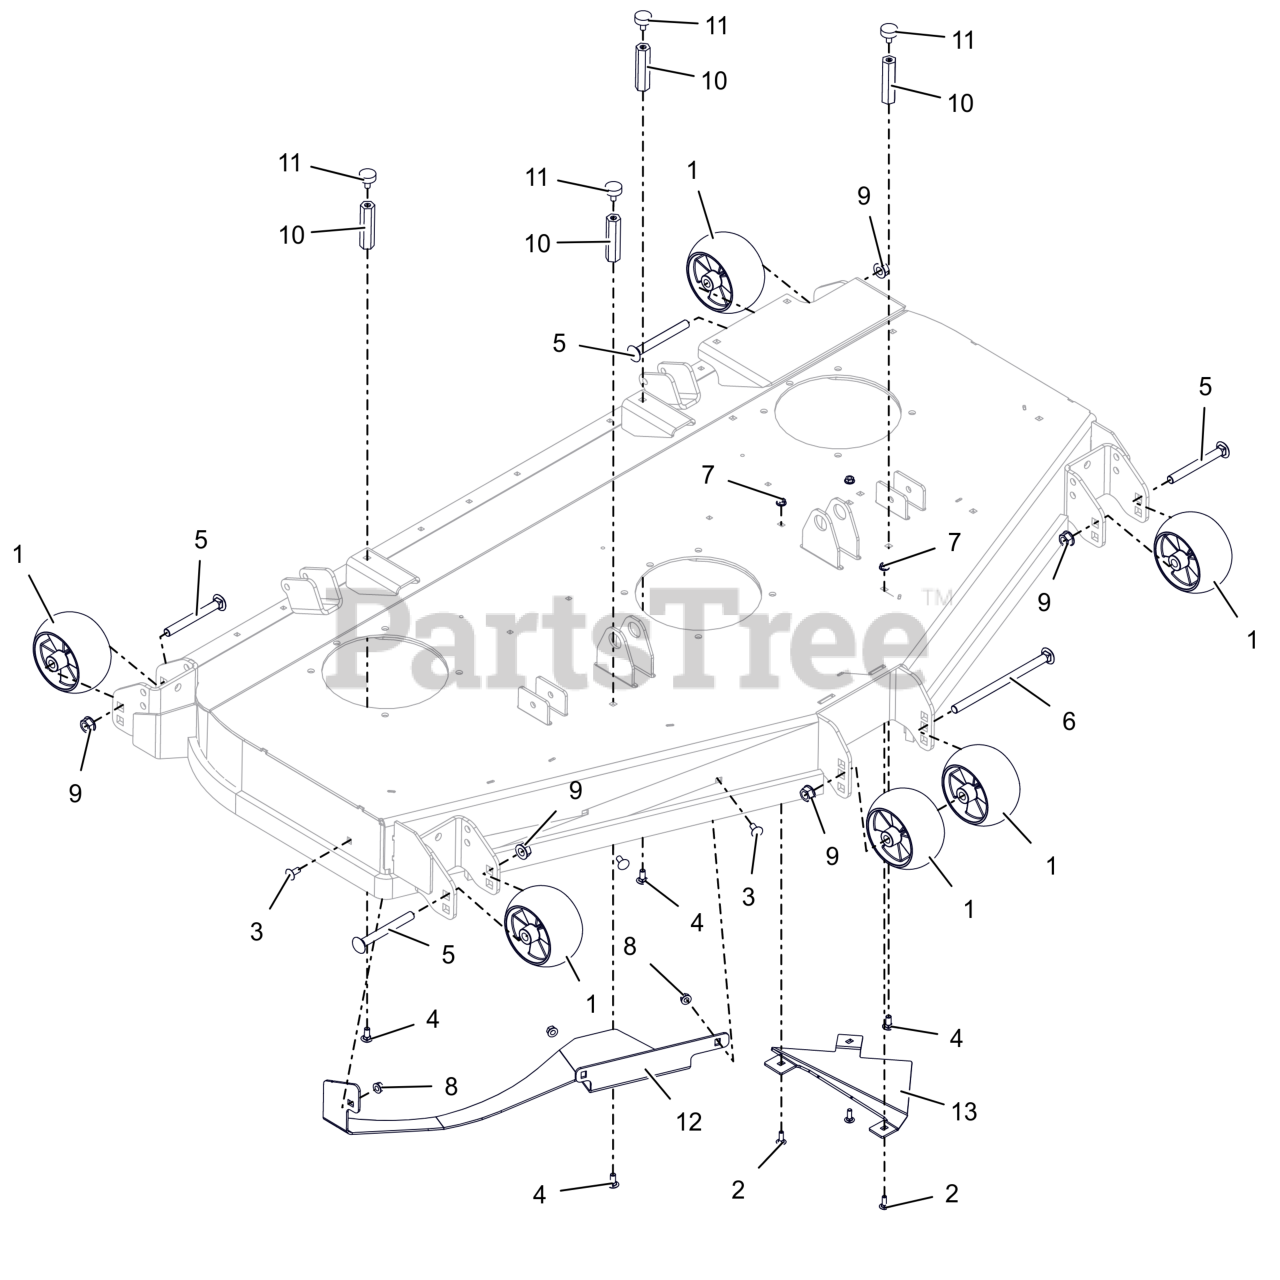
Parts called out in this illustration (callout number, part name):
1	WHEEL, ANTI SCALP - 5X3 CTR W/RIBS
2	BLT, RHSN .25-20X.750 G5 ZCC
3	BLT, RHSSN.31-18X.750 G5 ZCC
4	BLT, RHSN .31-18X.75 G5 ZCC LT
5	BLT-RHNS .50-13X4.50 G5 ZCC NS
6	BLT-RHSN .50-13X8.00 G5 ZCC NS
7	NUT-LK-CTR-FLG .25-20 ZC120
8	NUT,LK-CTR-FLG .31-18 GF ZCC
9	NUT-LK-CTR-FLG .500-13 GG ZCC
10	NUT, COUPLING .31-18 X 3.00
11	BUMPER, RUBBER
12	DEFLECTOR, BAFFLE BOLT-IN (ORANGE)
13	BAFFLE, INSERT TRIANGLULAR (ORANGE)
